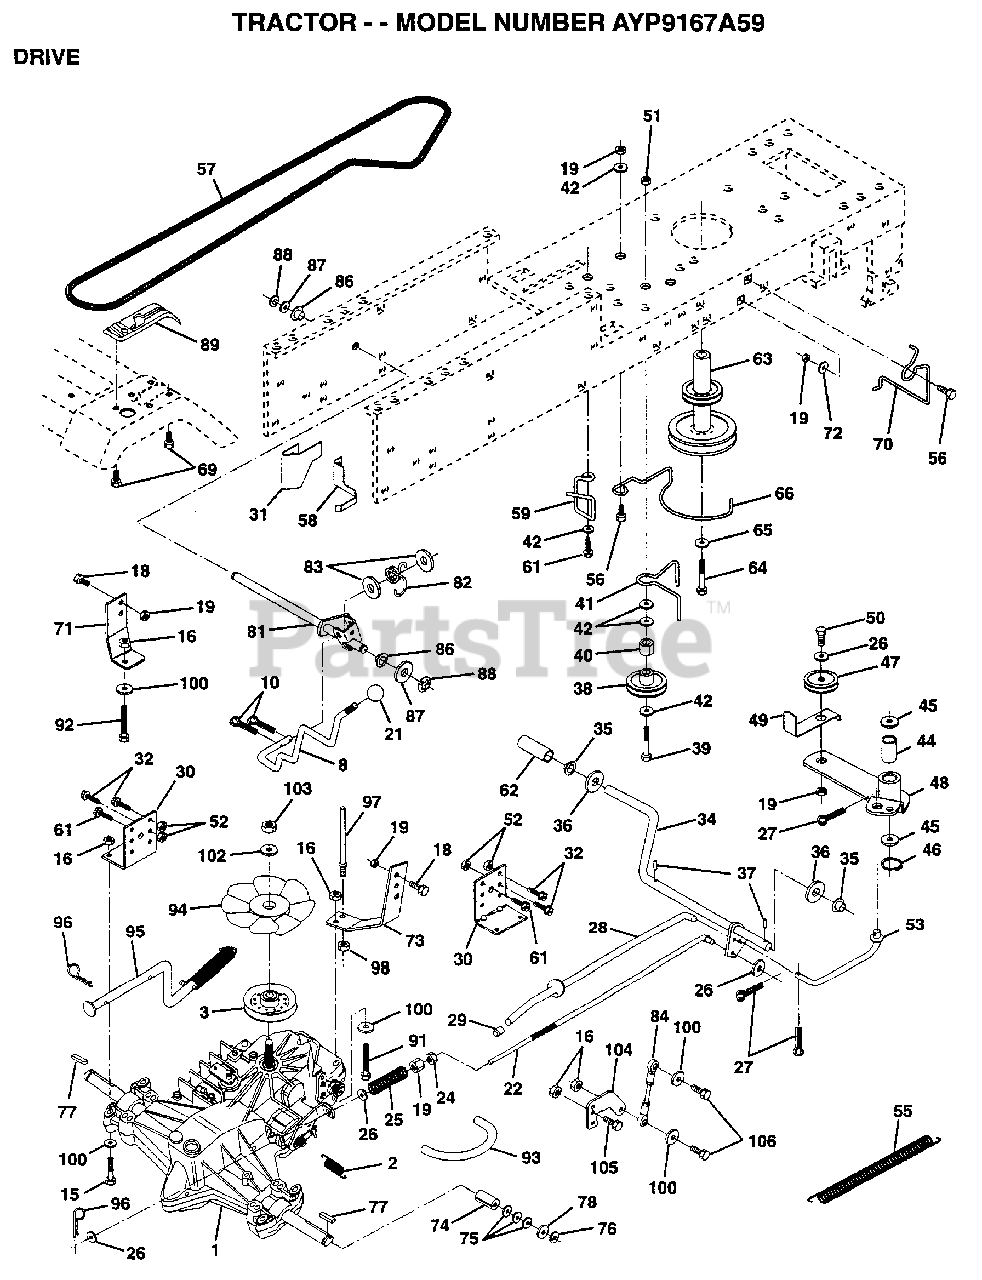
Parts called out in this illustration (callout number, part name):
2	SPRING RET BRAKE
3	PULLEY.TRANSAXLE
8	ROD SHIFT FEND YT
10	PIN COTTER 1/8
15	BOLT HEX
16	NUT
18	BOLT
19	NUT
21	KNOB T (1/2-HOLE)
22	ROD.BRAKE.HYDRO.
24	NUT
25	SPRING ROD LT
26	WASHER
27	COTTER PIN
28	ROD.BRAKE.PARK.LT
30	TRANSAXLE MTG BKT
31	"KEEPER,BELT LH T"
32	BOLT
35	NYLON BEARING
36	WASHER LT
38	PULLEY.IDLER.FLAT
39	BOLT
40	SPACER T
41	BELT KEEPER LT
42	WASHER
44	"LY, BEARING"
45	WASHER LT
46	KLIP RING
48	ARM IDLER
49	RETAIN BELT
53	"LINK, CLUTCH T"
55	"SPRING, RETURN LT"
57	"BELT.GD DRV 82"""
58	KEEPER BELT LH
59	KEEPER BELT CNTSP
61	SCREW
62	PEDAL COVER T
63	PULLEY.ENGINE
64	BOLT
65	LOCKWASHER
66	"MANUAL,OWNERS"
69	SCREW HEXWSH H-L
70	KEEPER BELT ENG
71	STRAP TORQ LH HYD
72	WASHER
73	STRAP TORQ RH HYD
74	SPACER SPLIT
75	WASHER
76	E-RING LT
77	SQUARE KEY
78	WASHER
82	"SPRING,TORSION"
83	WASHER
84	ROD.TIE.BALL.4.75
86	BUSHING
87	WASHER D
88	KLIP RING
92	HEX BOLT
93	"LINE FUEL HYD 4"""
94	"FAN 7"" HYDRO"
96	RETAINER M
97	BOLT KEEPER RH
98	NUT
100	WASHER M
102	WASHER BELLEVILLE
104	ARM CONTROL HYDRO
105	SCREW CAP 5/16-18
106	BOLT
